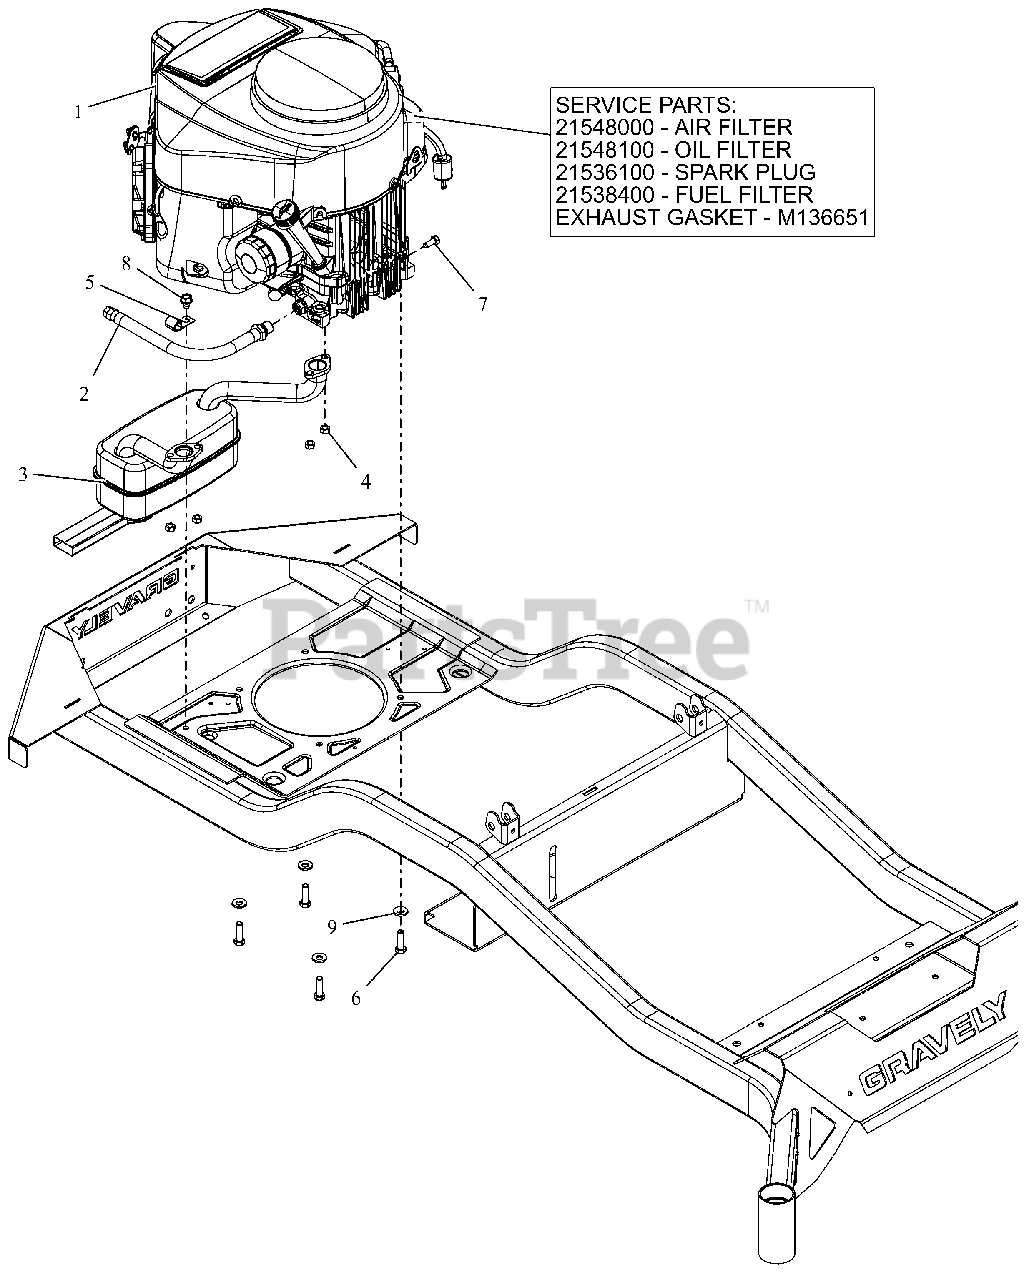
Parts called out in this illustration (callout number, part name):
1	ENGINE, KAWASAKI FR651V
1	AIR FILTER, KAWASAKI FR
1	OIL FILTER, KAWASAKI FR
1	PLUG, SPARK
1	FUEL FILTER - KAWASAKI
1	GASKET, MUFFLER #
2	HOSE, OIL DRAIN
3	MUFFLER, KAWASAKI
4	NUT-LK-TOP M8-1.25 YWZC
6	BLT-HEX.38-16X1.25 G5YZ NYTORQ
7	BLT, HEX M8-1.25X20 G8.8 ZCC
8	@SCR-TAP .38-16X.50 HWH TR YWZ
9	WASHER, 3/8" SPRING DISC
